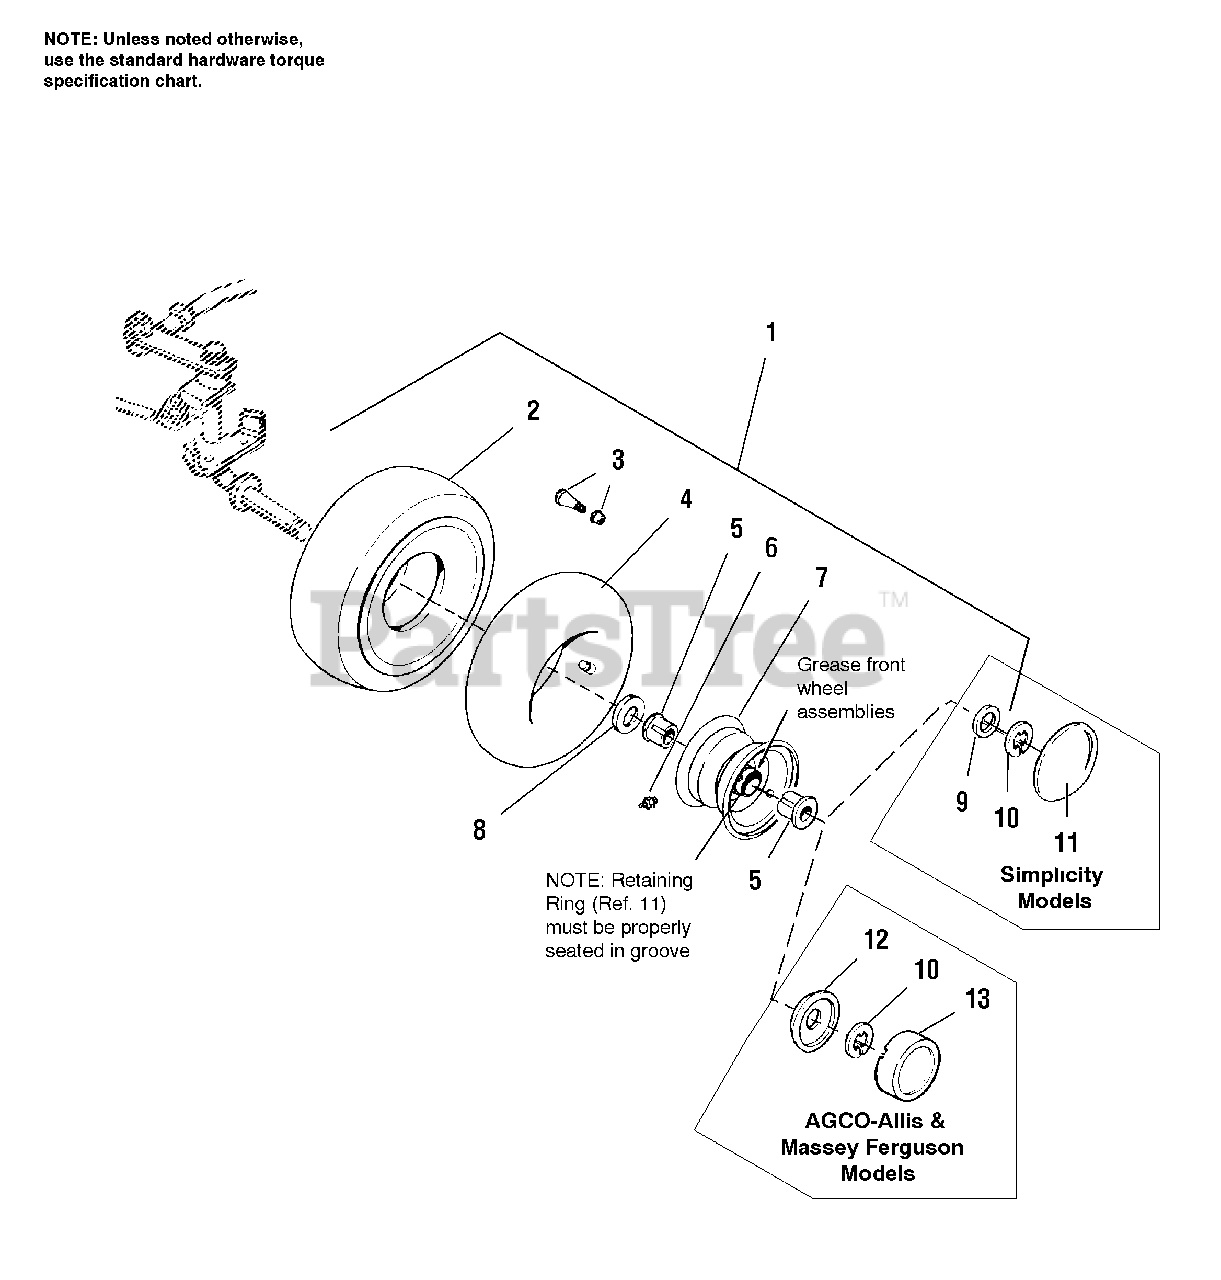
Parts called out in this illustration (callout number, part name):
1	WHEEL & TIRE ASSY. 15 x 6.00-6, Metallic Gray
2	TIRE, 15 x 6.00-6 (Dico)
3	VALVE STEM & CAP
4	TUBE, 4.10/3.50-6
5	BEARING
6	GREASE FITTING
7	WHEEL ASSY., Metallic Gray
8	WASHER, 3/4
9	WASHER, 3/4
10	RING, Retaining
11	HUBCAP, 6"
12	RETAINER, Cap, Hub
13	CAP, Hub
